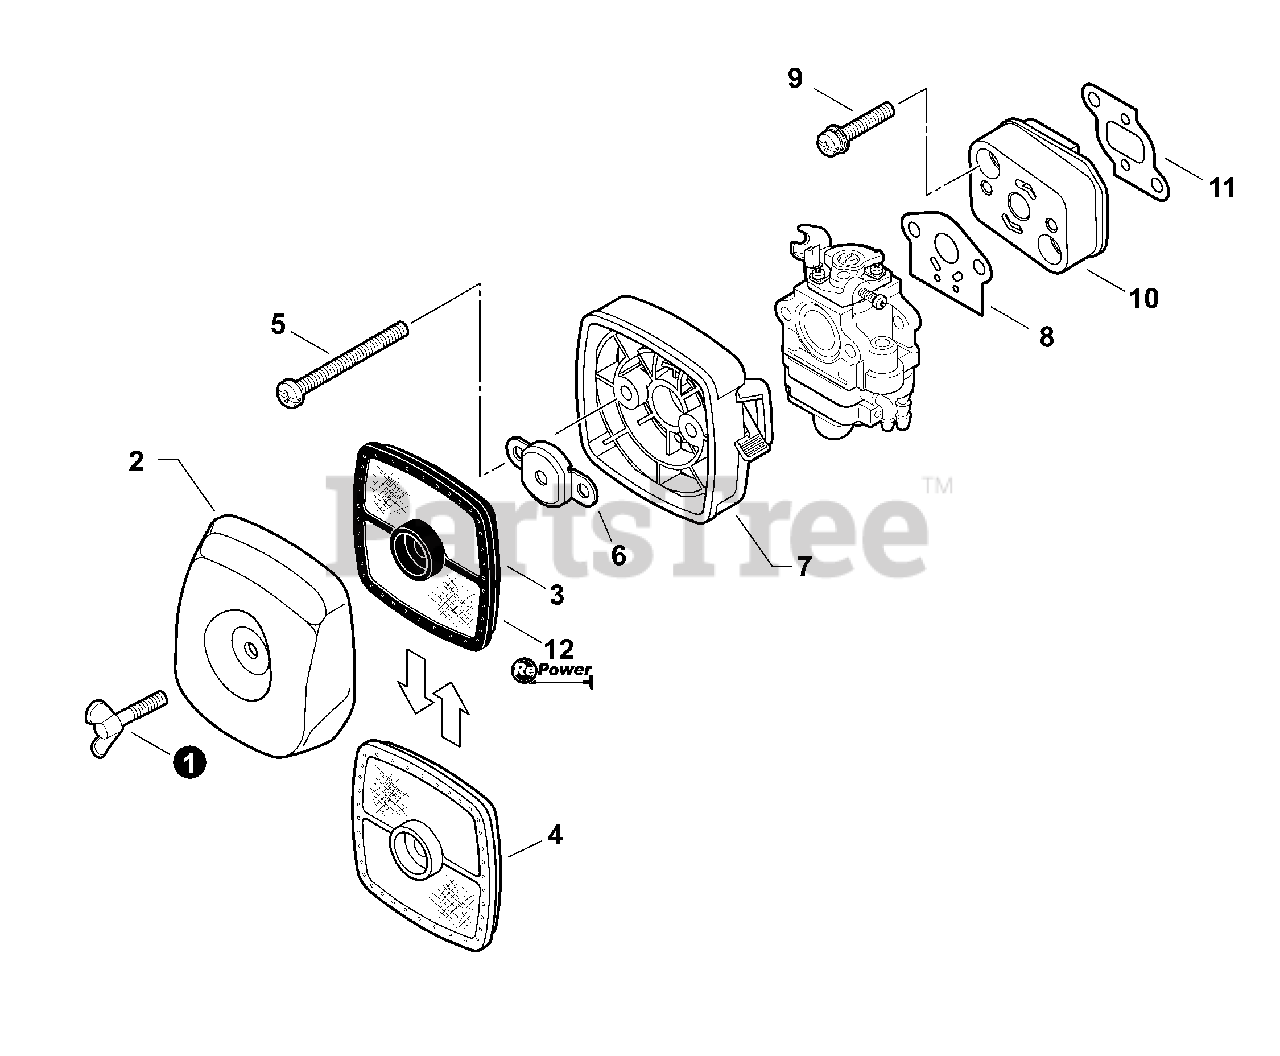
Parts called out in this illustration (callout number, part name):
1	THUMBSCREW
2	COVER, AIR CLEANER - BLACK
3	FILTER, AIR - DOUBLE LAYER
4	FILTER, AIR - SINGLE LAYER
5	SCREW - 5×60
6	PLATE, PREVENT
7	CASE, AIR CLEANER - BLACK
8	GASKET, INTAKE
9	SCREW - 5×25
10	INSULATOR, INTAKE
11	GASKET, INTAKE
12	RePower TUNE-UP KIT
12	RePower FILTER KIT
